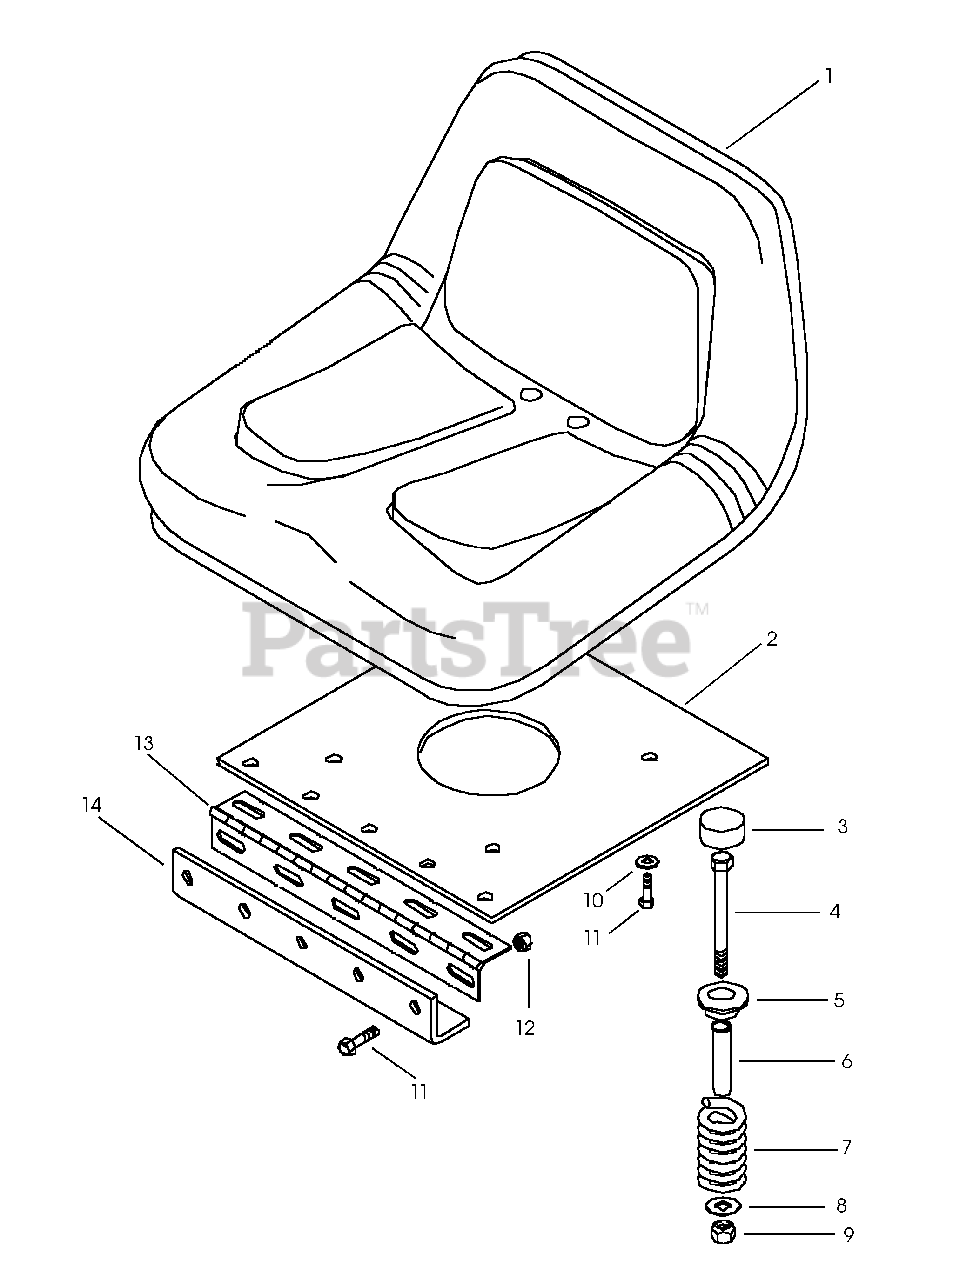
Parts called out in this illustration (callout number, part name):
1	Seat High Back
1	Kit-Arm Rest
2	Plate-Seat Mounting
3	Molded Cap 1.5 OD - 1.0 ID
4	Bolt-Hex .25-20 x 2.25 Grade 5
5	Cap-Valve Spring
6	Bushing-Split Rolled
7	Spring-Compression .149 x 1.095 x 1.75
8	Washer-Flat-Steel .344 x .688 x .065
9	Nut-Locking-Center .25-20
10	Washer-Locking .31 x .078
11	Bolt-Hex .31-18 x .63 Grade 5
12	Nut-Locking-Nylon w/insert .312-18 Grade 2
13	Hinge
14	Bracket-Seat Support
